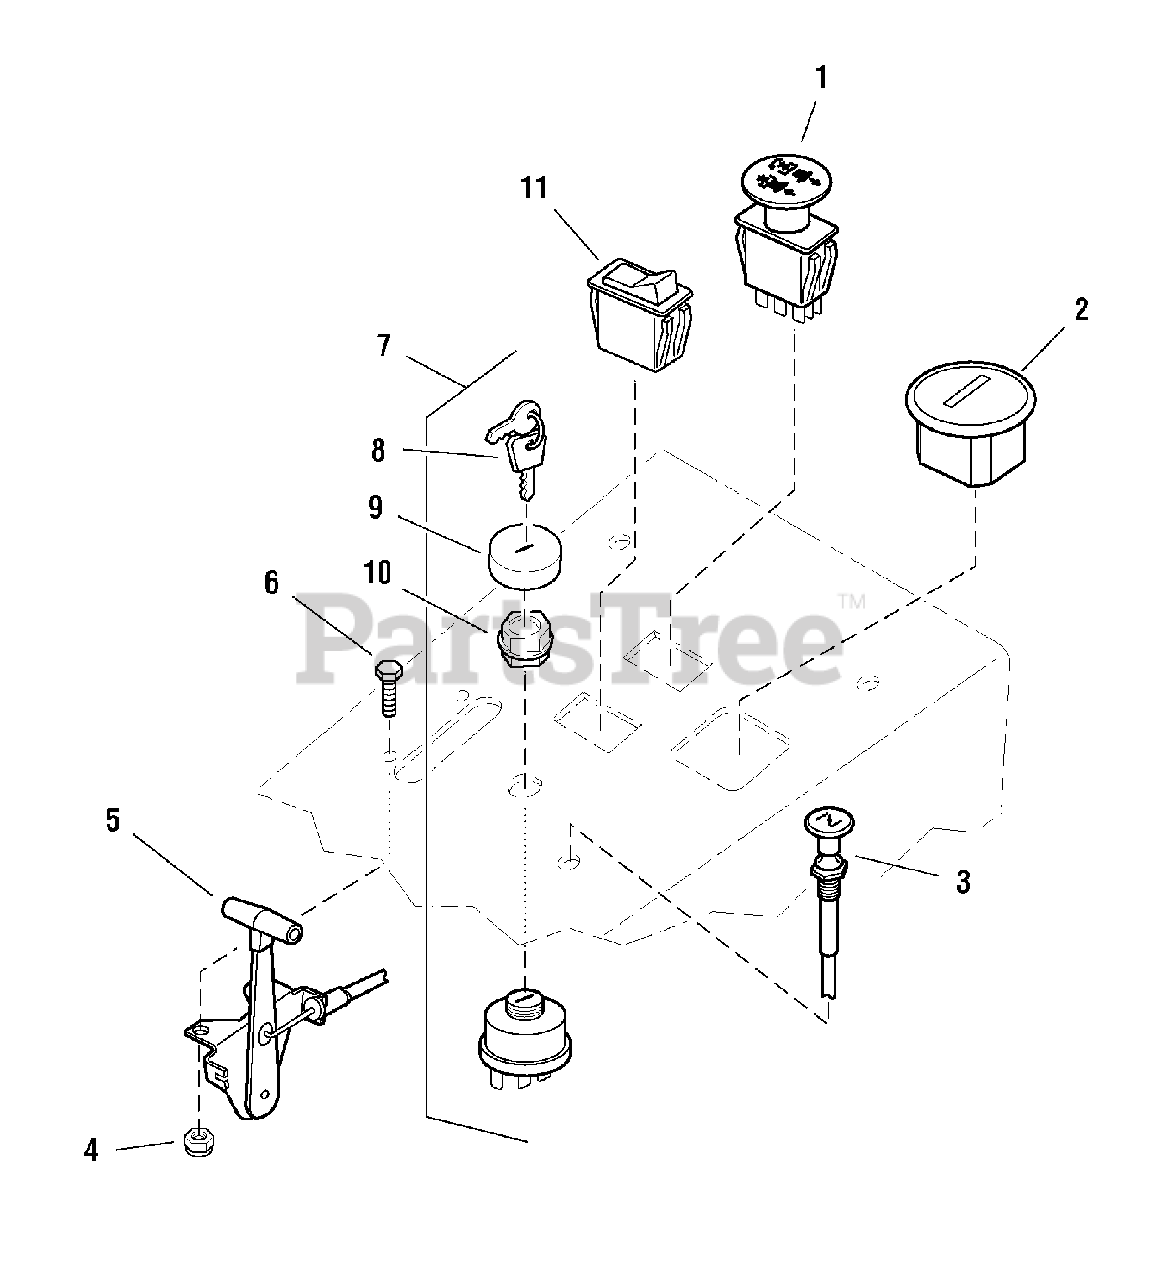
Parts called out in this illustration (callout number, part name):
1	SWITCH, PTO
3	CABLE, Choke Control
4	NUT, Hex, Nylon Lock, 1/4-20
5	CABLE, Throttle Control
6	CAPSCREW, Hex Hd, 1/4-20 x 3/4
7	SWITCH, Ignition, Complete (includes Ref 8-10)
8	KEY, Ignition, Molded (Set of 2)
10	PLASTIC NUT
11	SWITCH, Headlight
